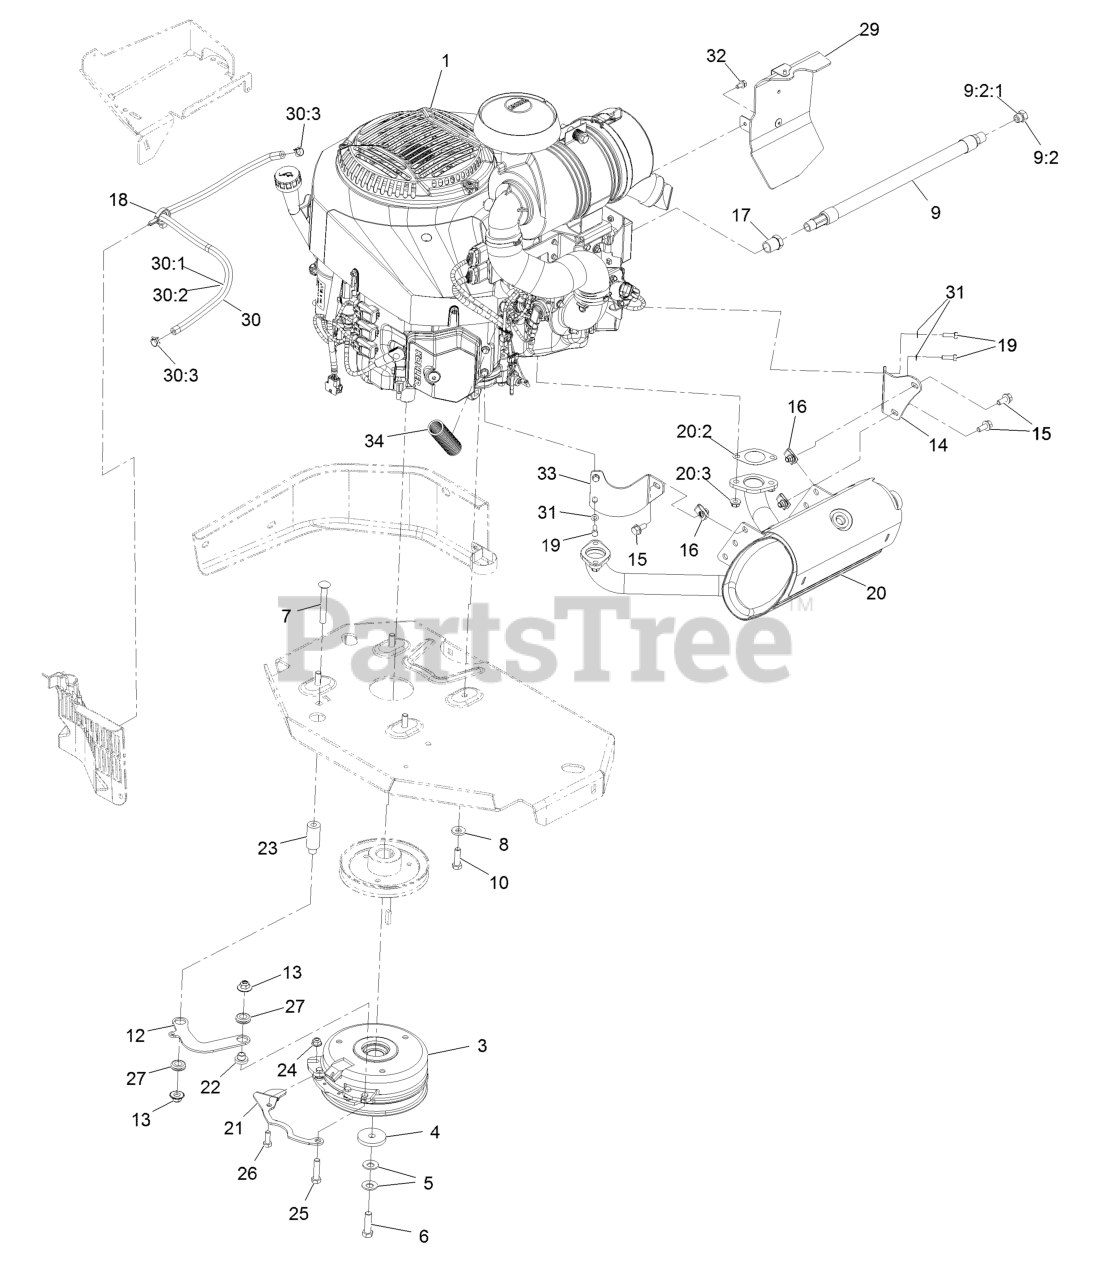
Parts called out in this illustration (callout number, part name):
3	Clutch, Cms250
3	Clutch Kit
4	Washer-Clutch
5	Washer-Spring Disc 7/16
6	Screw-HH 7/16-20 X 1 1/2 W/Loctite
7	Bolt-Carriage 3/8-16 X 3
8	Washer-Spring Disc 3/8
9	Oil Drain Hose ASM
9:2	Plug-W/O-Ring
9:2:1	O-Ring
10	Screw-HH 3/8-16 X 1 1/4
12	Link-Anchor, Clutch
13	Nut-Nyloc 3/8-16 Flg
14	Bracket-Muffler
15	Screw-HH Flg 5/16-18 X 3/4
17	Bushing
18	Clamp-Hose
19	Screw-HH M6-1 X 20Mm W/Patch
20	Muffler-940-980 Koh Efi
20	Muffler-Kit
20:2	Gasket-Exhaust
20:3	Nut-Flange, Lock
21	Belt-Guide
24	Nut-Nyloc 5/16-18 Flg
25	Screw-HH 3/8-16 X 1 1/2
26	Screw-HH 5/16-18 X 7/8
27	Grommet-Rubber
29	Rear Baffle ASM
30	ASM, Fuel Line
30:1	Hose-Fuel Line 29"
30:2	Sleeve, Thermal
30:3	Clamp-Hose
31	Washer-Spring Disc 1/4
32	Screw-HWH M6-1 X 12Mm Tf
33	Bracket-Muffler, Front
34	Conduit-Convoluted
